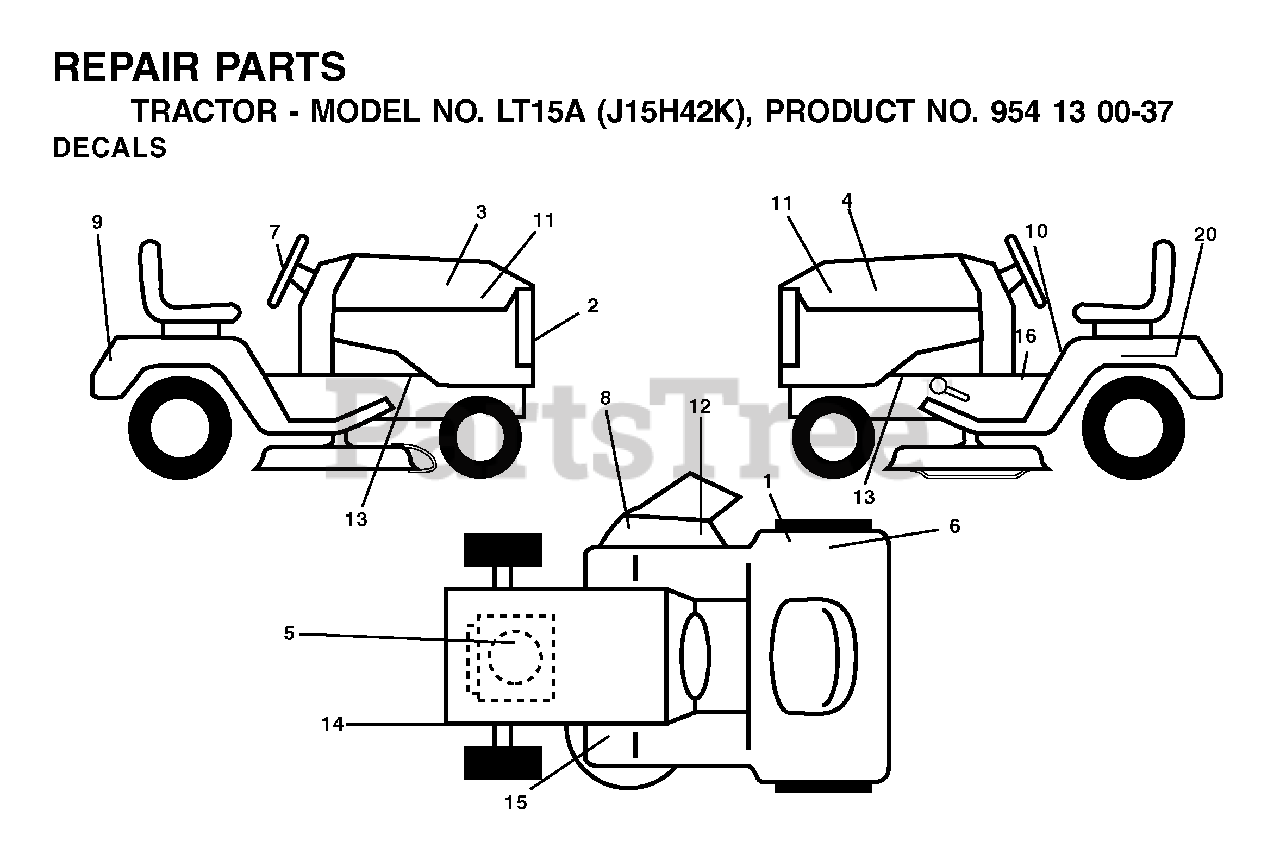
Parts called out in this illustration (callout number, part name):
1	DECAL CERTIFICATION
6	DECAL EUROPE STANDARD CE
8	DECAL MOWER CUT/FINGER
10	DECAL READ OWNER'S MAN SYMS
12	DECAL DECK "B" 42"
14	DECAL V BELT SCHEMATIC
16	DECAL PARK BRAKE
20	DECAL BTRY SYMBOLS
